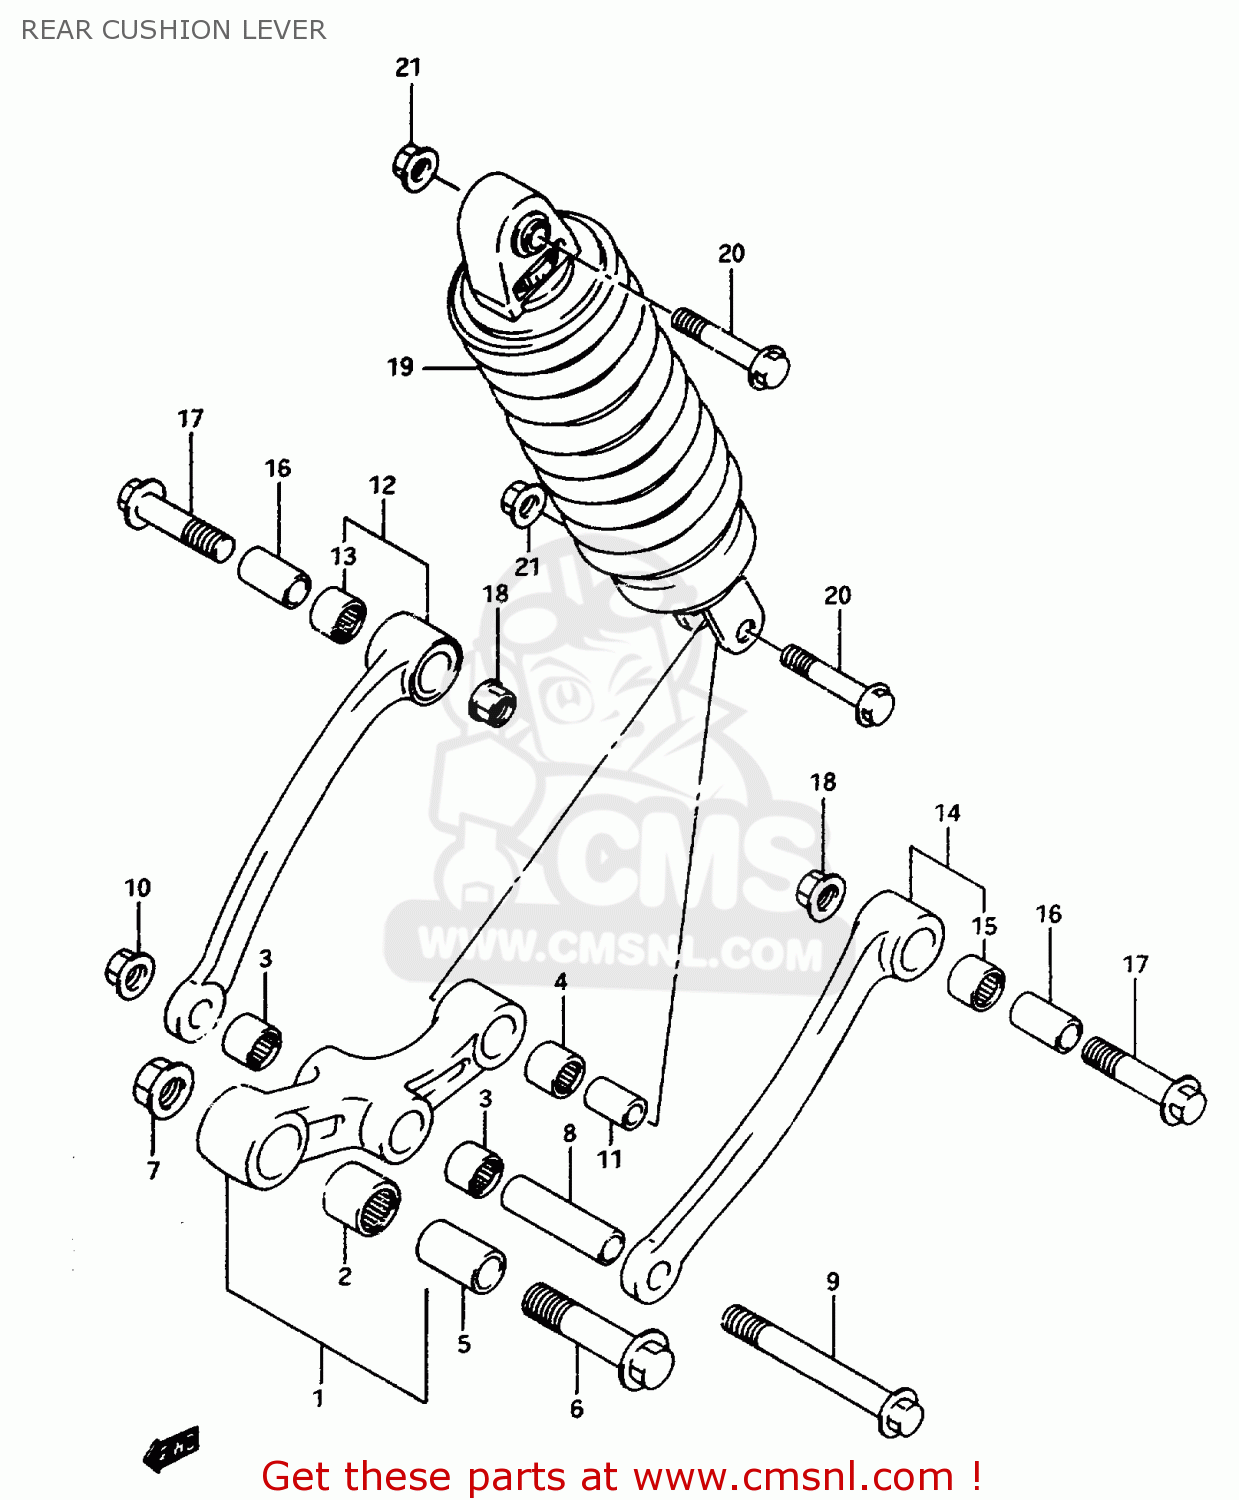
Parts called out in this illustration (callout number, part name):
1	LEVER SET,RR CUSHION
2	BEARING(20X27X30)
3	BEARING(17X24X25)
4	BEARING(17X24X26)
5	SPACER(14X20X34)
6	BOLT(14X62)
7	NUT 14MM
8	SPACER(12X17X60)
9	BOLT(12X96)
10	NUT 12MM
11	SPACER,RR CUSHION LEVER
12	ROD SET,RR CUSHION,R
13	BEARING(17X24X26)
14	ROD SET,RR CUSHION,L
15	BEARING(17X24X26)
16	SPACER(12X17X29)
17	BOLT L:52
18	NUT 12MM
19	ABSORBER ASSY,RR SHOCK
20	BOLT(10X52)
21	NUT 10MM
